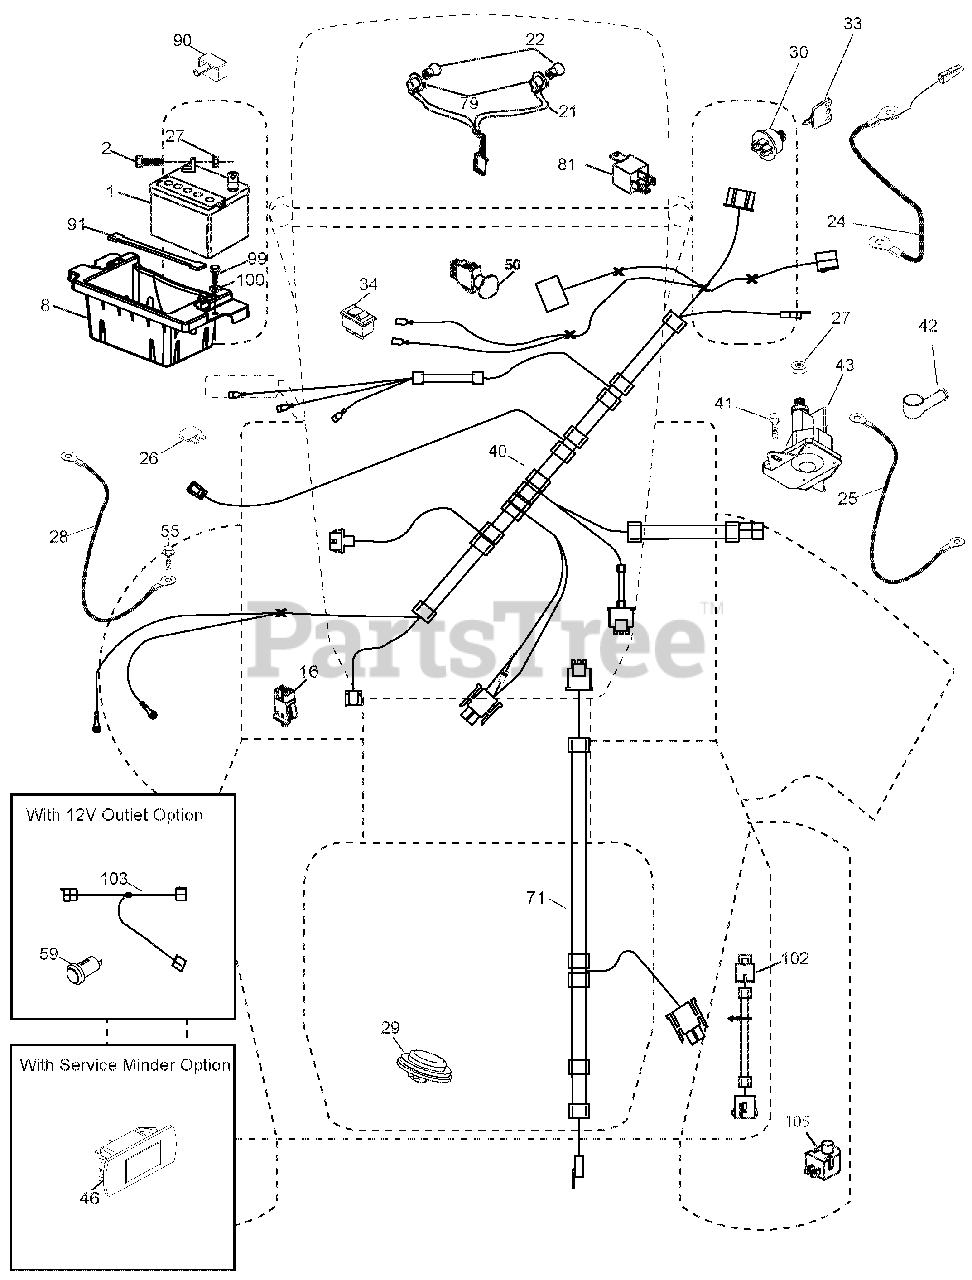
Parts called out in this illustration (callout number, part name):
1	BATTERY.12.VOLT.28.AMP.WET
2	BOLT.HEX.HD.1/4-20UNC X 3/4
8	BOX.BATTERY.MOUNT.FRONT.LT
16	SWITCH.INTERLOCK.NONO.GRAY
21	HARNESS ASM.LIGHT.22"(4152J)
22	BULB.LIGHT.#1156
24	CABLE.BTRY.PSWRE.DSH SOL.8"TEX
25	CABLE.STARTER.6GA.BL/RED.14.5"
26	FUSE.20 AMP.
27	Nut, Keps Hex 1/4-20 unc
28	CABLE.GROUND.21"BLK.6 GA.90T
29	SWITCH.SEAT.DELTA.OPC.9LB.
30	SWITCH.IGN.DLTA.P-IN.ROS
33	KEY/CHAIN.BLISTER PACK.GEN.USA
34	SWITCH.LIGHT/RESET.B/B/RED.
40	HARNESS IGN ELEC RELAY
41	Screw 1/4-20 x 1/2
42	COVER.TERMINAL.RED
43	SOLENOID.W/BRASS PLUNGER.2005
46	HOUR METER
50	SWITCH.PTO.8 TERMINAL.BLACK
55	SCREW.5/16-18X3/4.SMGML.TAP/R
71	HARNESS.IGN.CHASSIS.TEX
79	SOCKET ASM.BULB.TWISTLOCK
81	RELAY HARNESS SEALED
90	COVER.TERMINAL.BATTERY.FR.TEX
91	STRAP.BATTERY.MOUNT.FRONT
99	SCREW.HEXWSH.THDROL.1/4-20X3/4
100	WASHER.9/32 X 7/8 X 16GA.
102	HARNESS.PIGTAIL.K46.TEX.ROS
105	SWITCH.REVERSE.TT.PEDAL CONTRO
